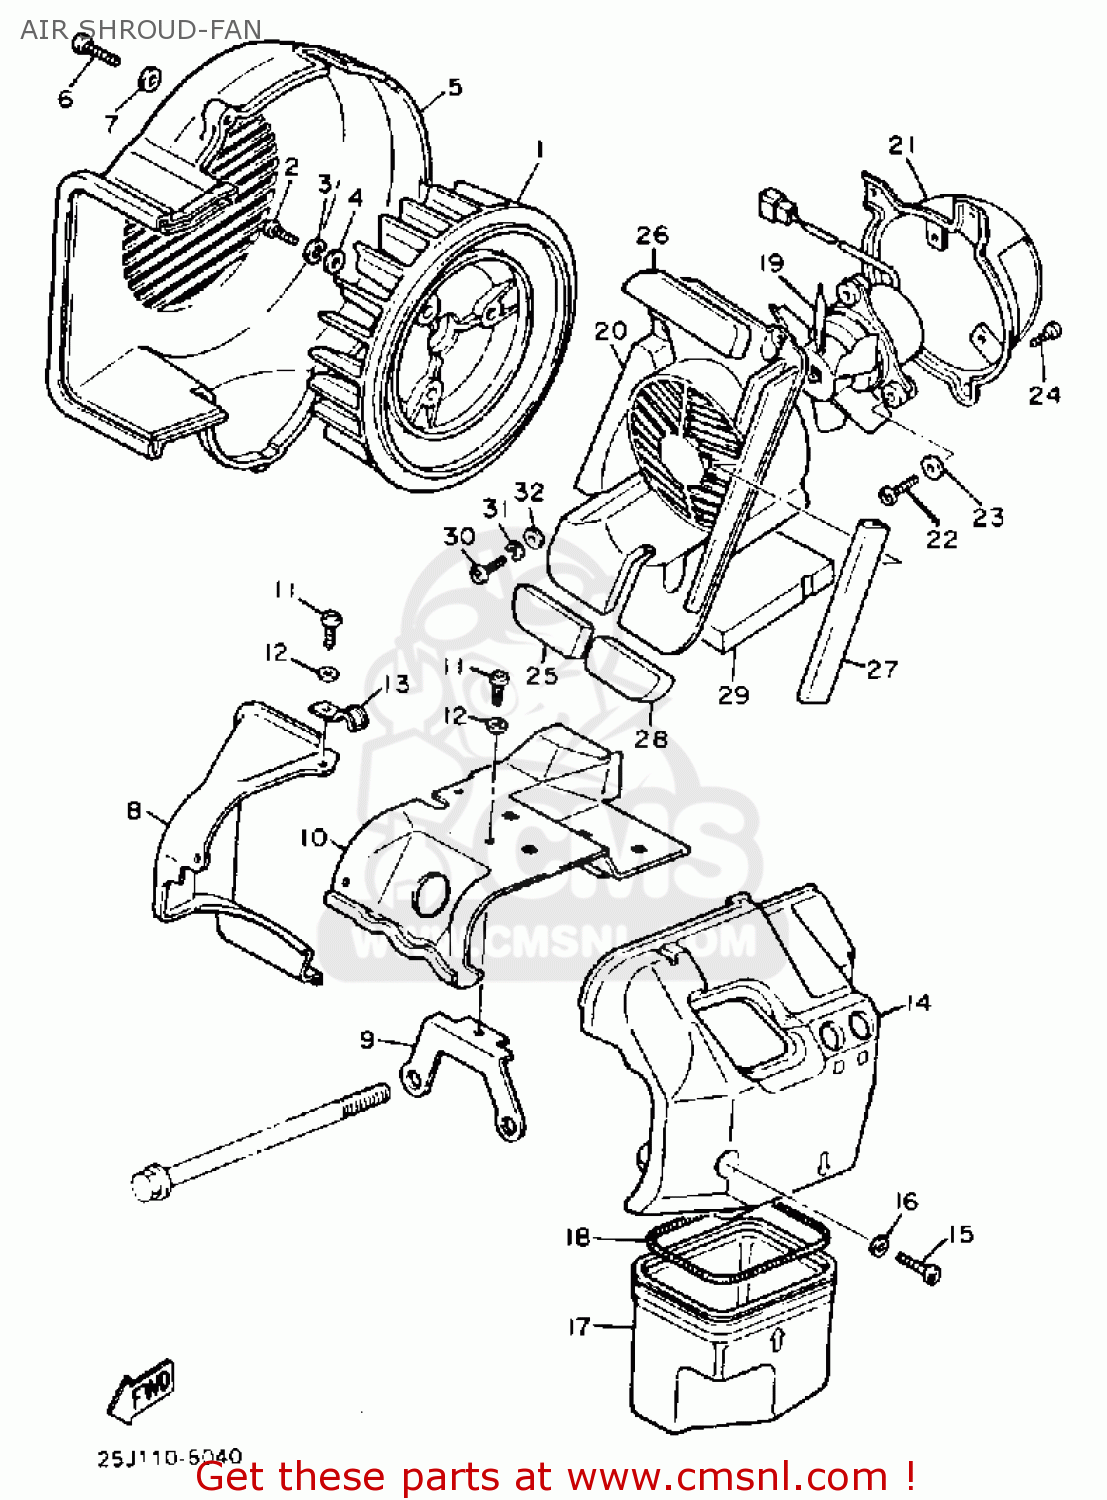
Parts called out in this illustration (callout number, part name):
1	FAN
2	SCREW, PAN HEAD (N151)
3	WASHER(6A1)
4	WASHER, PLATE (4H7)
5	COVER, FAN CASE
6	SCREW PAN HEAD
7	WASHER, PLATE (898 FRAME)
8	AIR SHROUD, CYLINDER 1
9	STAY 1
10	AIR SHROUD, CYLINDER 2
11	SCREW PAN HEAD
12	WASHER, PLATE (4H7)
13	CLAMP (7G5)
14	AIR SHROUD, CYLINDER 3
15	SCREW PAN HEAD
16	WASHER, PLATE (4H7)
17	DUCT
18	SPRING, COMPRESSION (25G)
19	MOTOR ASSY
20	CASE, FAN
21	CASE, FAN 2
22	SCREW, PANHEAD
23	WASHER (25G)
24	YBS83-525 SCREW,PANH.TAPPING
25	PAD, FAN CASE
26	PAD, FAN CASE 2
27	DAMPER, SHROUD 4
28	PAD, FAN CASE 3
29	DAMPER, SHROUD 5
30	SCREW PAN HEAD
31	WASHER,SPRING
32	WASHER, PLATE (898 FRAME)
